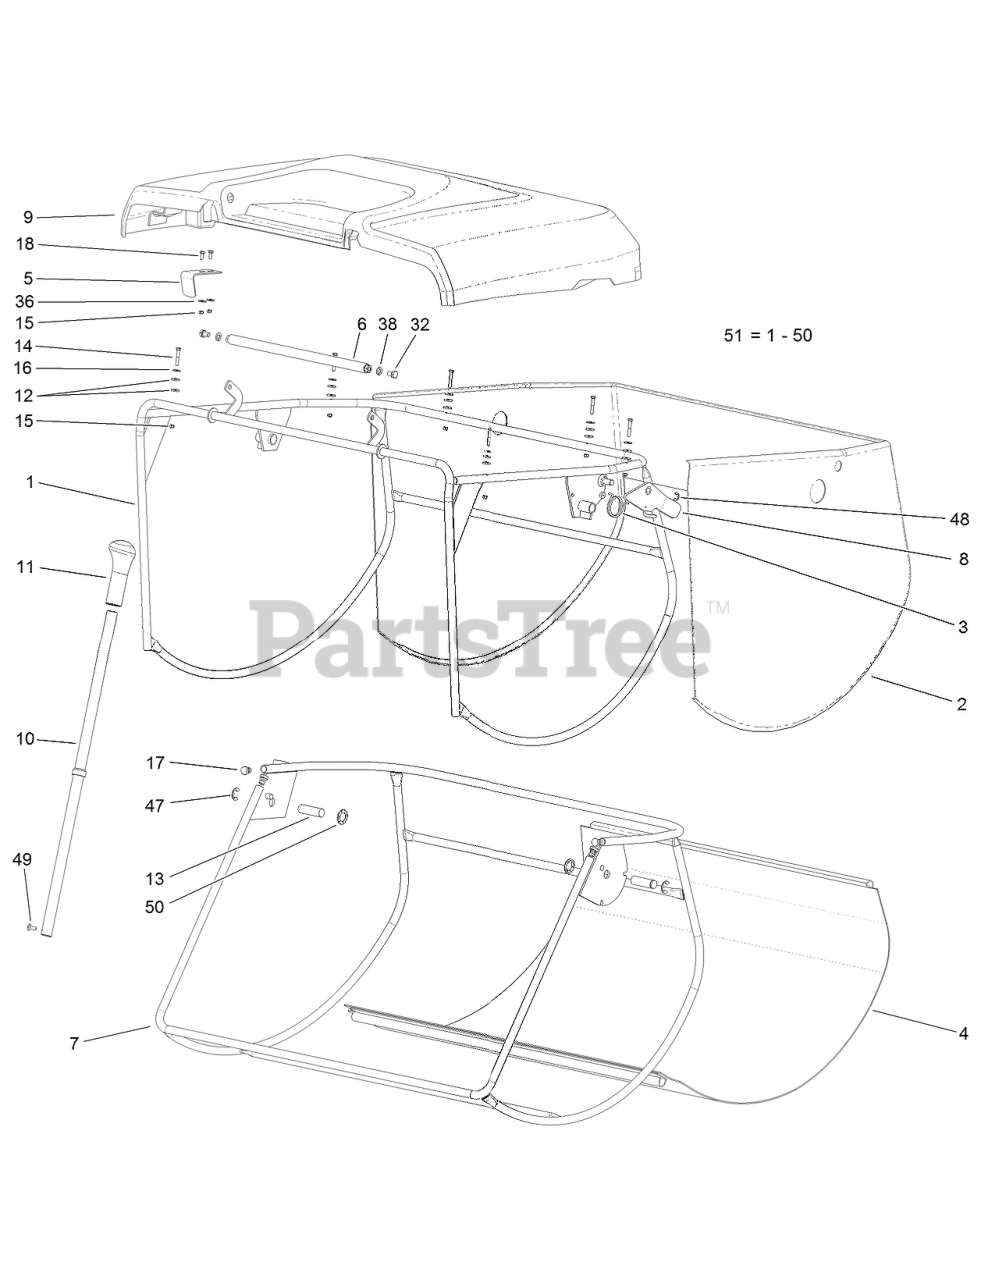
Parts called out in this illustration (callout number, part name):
1	FRAME ASM
2	BAG-GRASS, UPPER
3	SPRING
4	BAG-GRASS, LOWER
5	SPRING-COIL, INTERLOCK SWITCH
6	HANDLE-LIFT
7	LOWER FRAME ASM
8	LEVER-ARRESTMENT
9	COVER-COLLECTOR
10	LEVER-DUMP
11	HANDLE-MULCHING
12	WASHER-FLAT
15	NUT-LOCK
16	WASHER-RUBBER
32	SCREW-HHF
36	WASHER
38	WASHER-SPRING
47	E-CLIP
48	RING-LOCKING
50	RING-LOCK
51	GRASS COLLECTOR ASM
